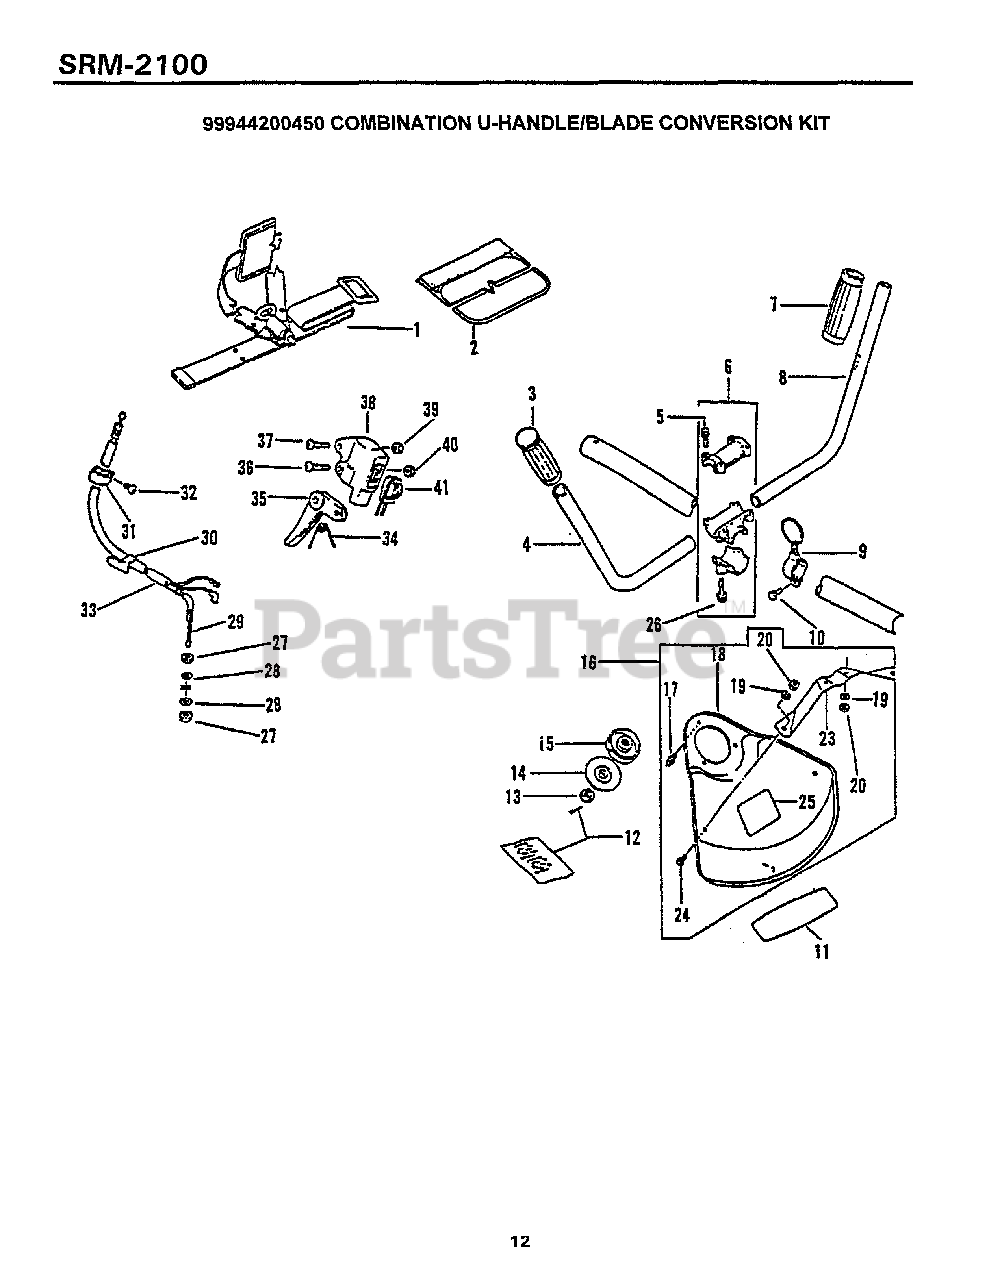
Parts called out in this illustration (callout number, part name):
1	Harness Asy
2	Pad, Waist
4	Handle (Left)
5	Bolt 5x25 (W/W SW)
6	Bracket Set
8	Handle (Right)
9	Hook
10	Bolt 5x12
11	Lable, Echo
12	Pin, Split
13	Nut 10, Left
14	Plate, Fitting (Lower)
15	Plate, Fitting (Upper)
16	Shield Asy
17	Screw 5x10
18	Shield
19	Washer, Spring 5
24	Screw 5x16
25	Lable, Caution
26	Bolt 6x30 (W/W, SW)
28	Washer 6
29	Cable, Throttle
32	Screw 5x10
33	Tube
34	Spring, Return
35	Trigger, Throttle
36	Screw 5x25
38	Bracket, Throttle
39	Locknut 5
41	Switch, Ignition
